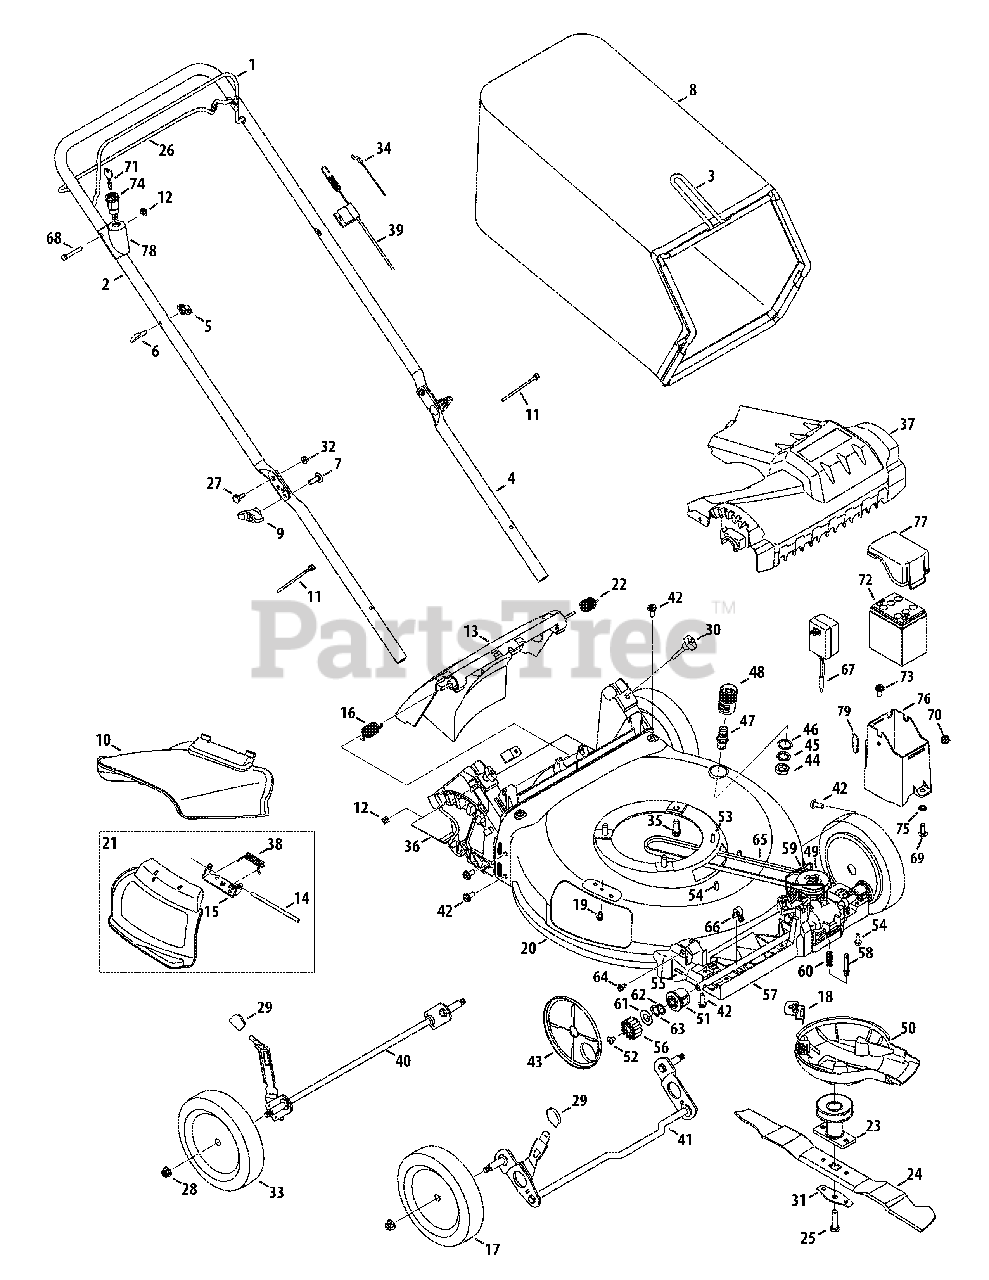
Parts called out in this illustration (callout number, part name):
1	Blade Control
2	Upper Handle
3	Grass Catcher Frame
4	Lower Handle
6	Rope Guide
7	Carriage Screw, 5/16-18
8	Grass Bag
10	Side Chute
11	Cable Tie
12	Nut, Sq., 1/4-20
13	Rear Discharge Door & Baffle Assembly-Generic
13	Rear Discharge Door & Baffle Assembly-Lowes
14	Hinge Pin
15	Chute Deflector Bracket
16	Torsion Spring - RH
17	Front Wheel
18	Engine Baffle Bracket
19	Screw, 1/4-20 x .500
20	Deck, 21"
21	Hinged Mulch Plug Assembly
22	Torsion Spring - LH
23	Blade Adapter Assembly
24	Mulching Blade
25	Screw , 3/8-24 x 1.50
26	Drive Control
27	Sldr. Screw, .375 x .126 x 1/4-20
28	Flange Lock Nut, 3/8-16
29	Adjustment Lever Knob
30	Wing Nut
31	Blade Bell Support
32	Nut, Flange Lock, 1/4-20
33	Rear Wheel
34	Control Cable
35	TT Sems Screw, 3/8-16 x 1.0
36	Trail Shield
37	Front Cover
38	Torsion Spring
39	Drive Cable
40	Rear Axle Assembly
41	Front Axle Assembly
42	Screw, 5/16-14 x .750
43	Wheel Dust Cover
44	Nut, Hex
45	Washer, Lock, 5/8"
46	Wash., Flat, .865 x 1.145 x .030
47	Water Nozzle
48	Water Nozzle Adapter
49	Transmission Assembly
50	Engine Baffle
51	Bearing Assembly
52	Screw, 1/4-20 x .390
53	Screw, 1/4-20 x .500
54	Screw, 1/4-15 x .750
55	Dowel Pin
56	Spur Gear, 14T - RH
56	Spur Gear, 14T - LH
58	Spring Body
59	Transmission Wire
60	Compression Spring
61	Wash., Flat, .508 x 1.00 x .020
62	Wash., Flat, .504 x .700 x .010
63	Wash., Saddle, .505 x .740 x .125
64	Scr., Sldr., 1/4-20 x .70
66	Front Axle Clip
67	Battery Charger
68	Screw, 1/4-20 x 1.75
69	Bolt, Carr., 5/16-18 x .875
70	Nut, Flglk., 5/16-18 x
72	Battery
73	Scr., Sldr., 5/16-14 x .972
74	Key Switch
75	Speed Nut
76	Battery Housing
77	Battery Housing Top
78	Electric Start Housing
79	Lid Seal
